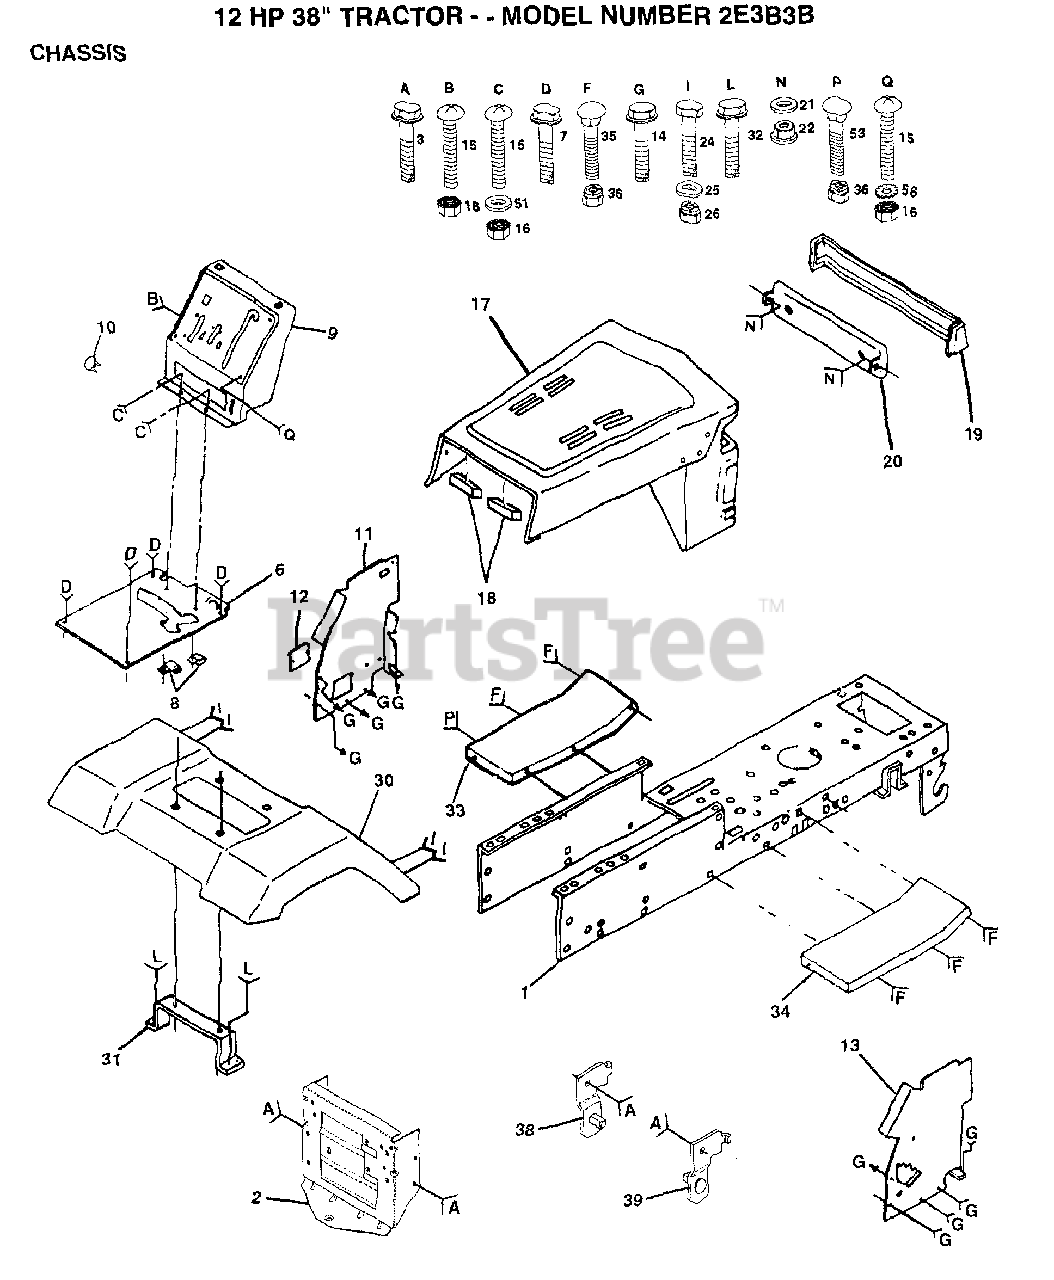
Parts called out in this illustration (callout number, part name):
3	SCREW
7	SCREW
8	CLIP T
9	DASH SILKSCRN 1
10	PLUG BUTTON T
11	PANEL DASH LH
12	COVER ACCESS
14	SCREW LT
15	SCREW
17	HOOD/GRILLE ASM SILKSCREEN WELDED
19	LENS SERVICE KIT
21	WASHER PM
22	PAL NUT LT
24	BOLT
25	WASHER
26	NUT
30	FENDER
31	BRKT FENDER
32	SCREW
33	FOOTREST LH
34	FOOTREST RH
35	BOLT
36	NUT
38	BRACKET ASM LH
39	BRACKET ASM RH
51	WASHER
58	LOCKWASHER
